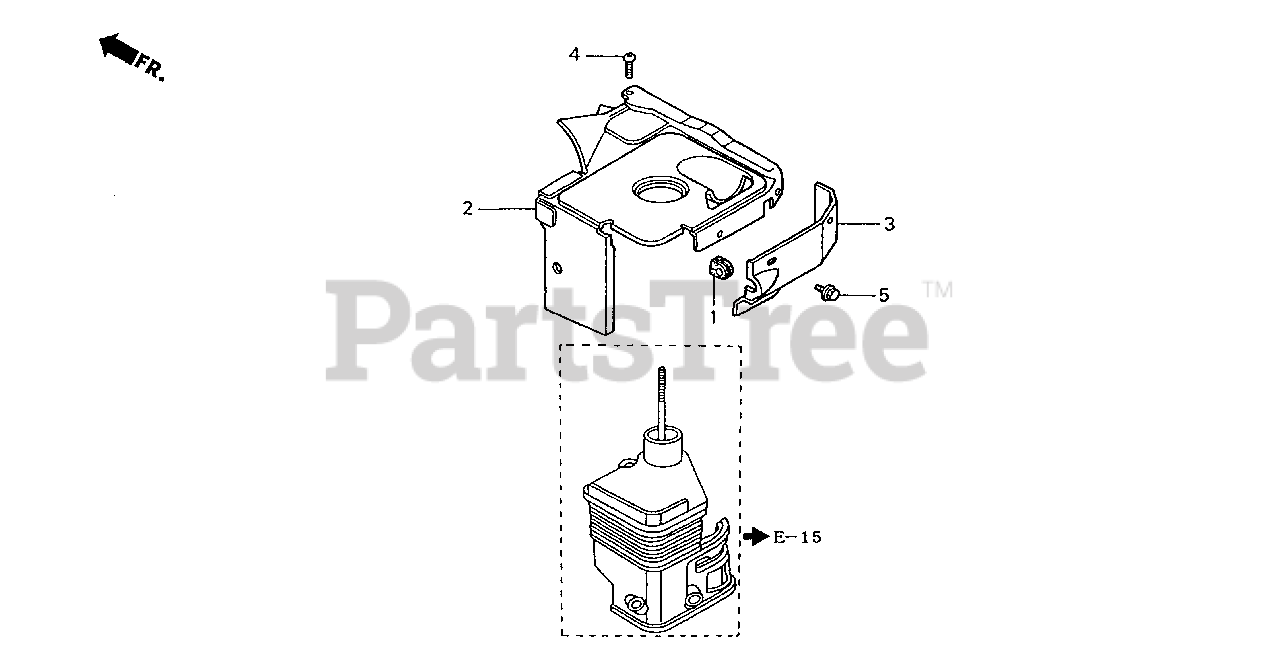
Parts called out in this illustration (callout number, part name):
1	GROMMET, OIL PIPE HOLDER
2	COVER, CONTROL
3	COVER, AIR IN.
4	SCREW, PAN (6X8)
5	BOLT, FLANGE (6X8)
